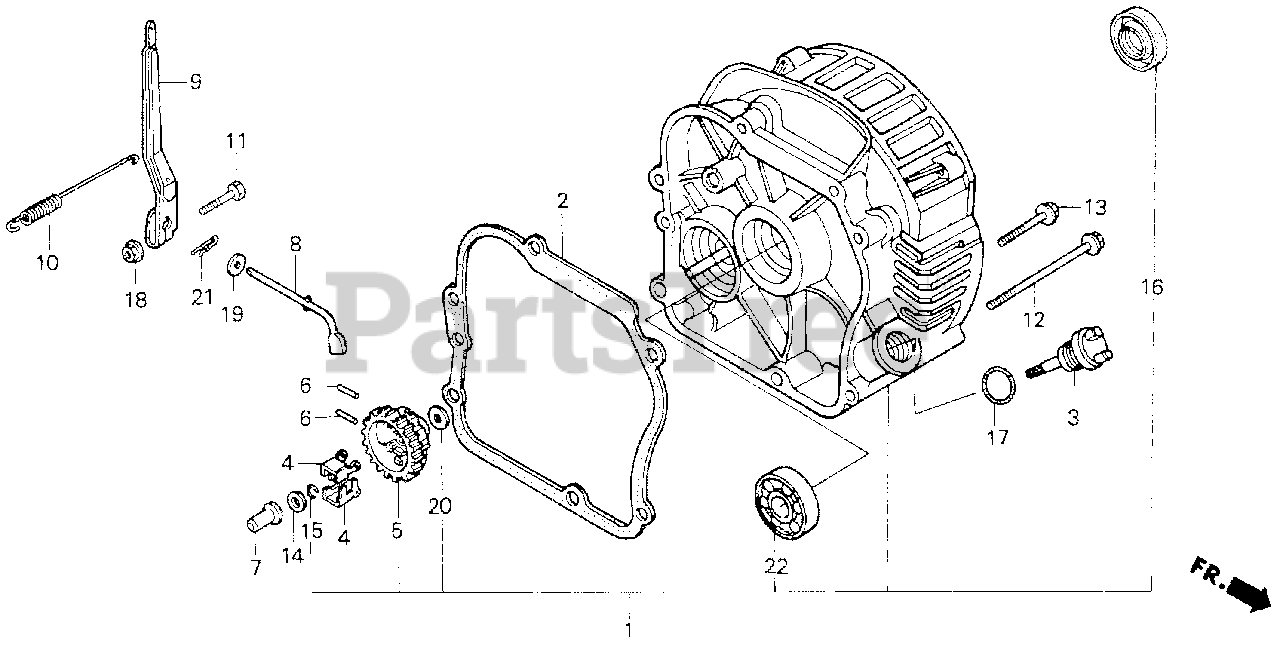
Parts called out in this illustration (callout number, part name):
1	COVER ASSY., CRANKCASE
2	GASKET, CASE COVER
3	CAP, OIL FILLER
4	WEIGHT, GOVERNOR
5	HOLDER, GOVERNOR WEIGHT
6	PIN, GOVERNOR WEIGHT
7	SLIDER, GOVERNOR
8	SHAFT, GOVERNOR ARM
9	ARM, GOVERNOR
10	SPRING, GOVERNOR
11	BOLT, GOVERNOR ARM
12	BOLT, FLANGE (6X65)
13	BOLT, FLANGE (6X28)
14	WASHER (6X16)
15	CLIP, GOVERNOR HOLDER
16	OIL SEAL (17X30X6) (NOK)
17	O-RING (16MM)
18	NUT, FLANGE (6MM)
19	WASHER, PLAIN (5MM)
20	WASHER, PLAIN (6MM)
21	PIN, LOCK (8MM)
22	BEARING, RADIAL BALL (6203)
